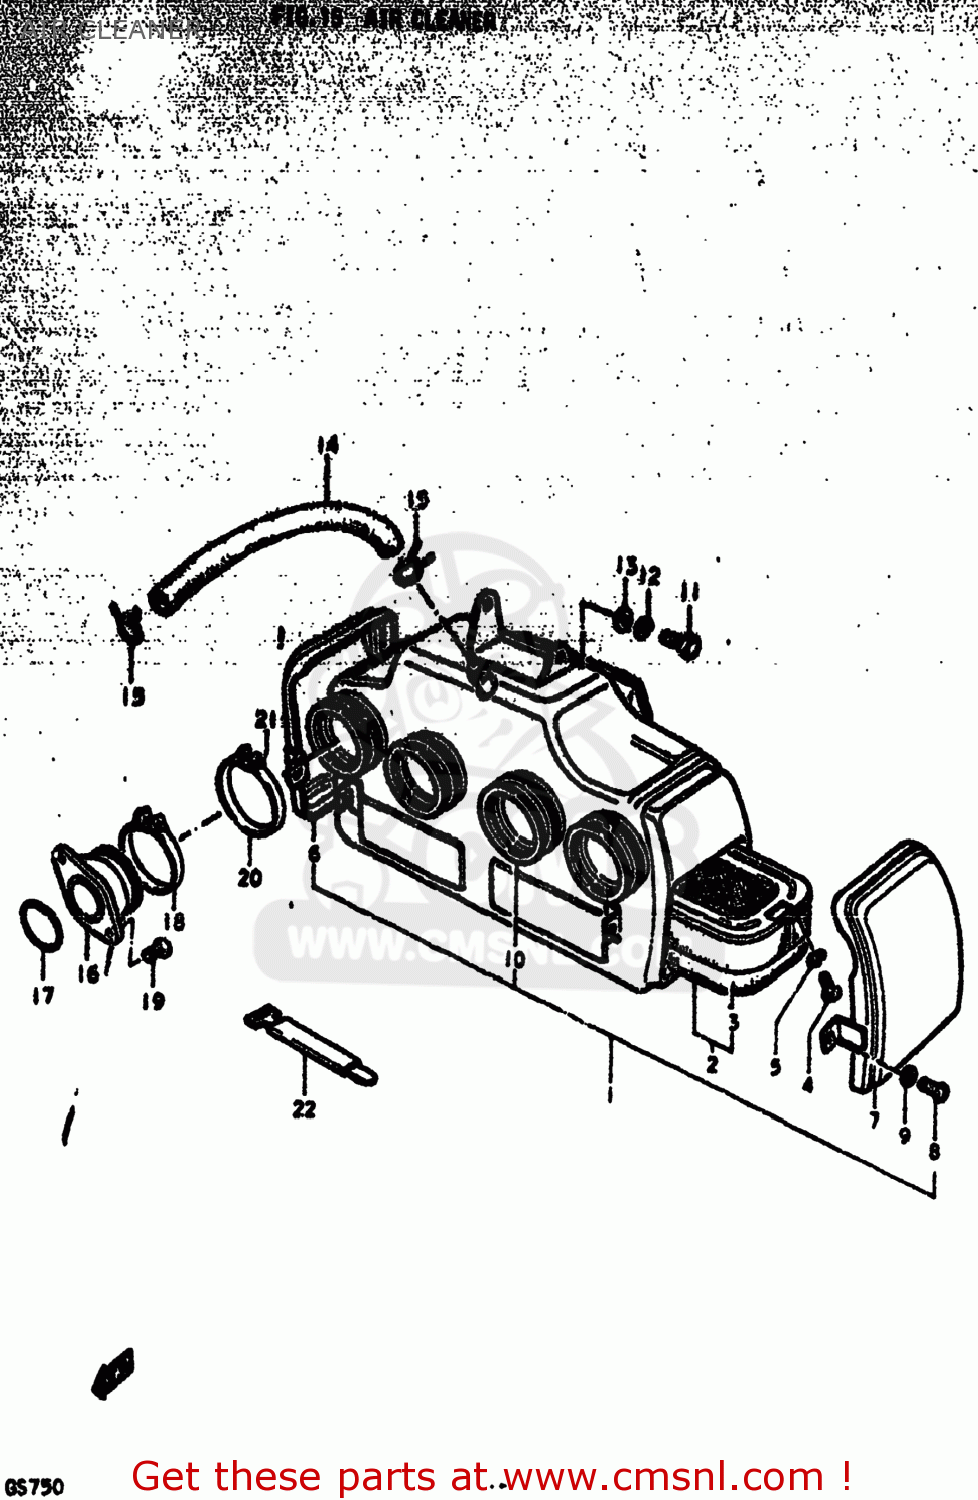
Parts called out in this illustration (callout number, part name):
1	CLEANER ASSEMBLY,AIR
2	FILTER ASSY,AIR CLEANER
3	FILTER
4	SCREW
5	LOCK WASHER
6	CAP,AIR CLEANER
7	COVER,AIR CLEANER,LEFT
8	SCREW
9	LOCK WASHER
10	HOSE
11	BOLT
12	LOCK WASHER
13	WASHER
14	HOSE
15	CLIP
16	PIPE,INTAKE
17	O RING(D:2.4,ID:31.7)
18	CLAMP
19	SCREW
20	CLAMP
21	SCREW TAPP.
22	CLAMP(L:120)
